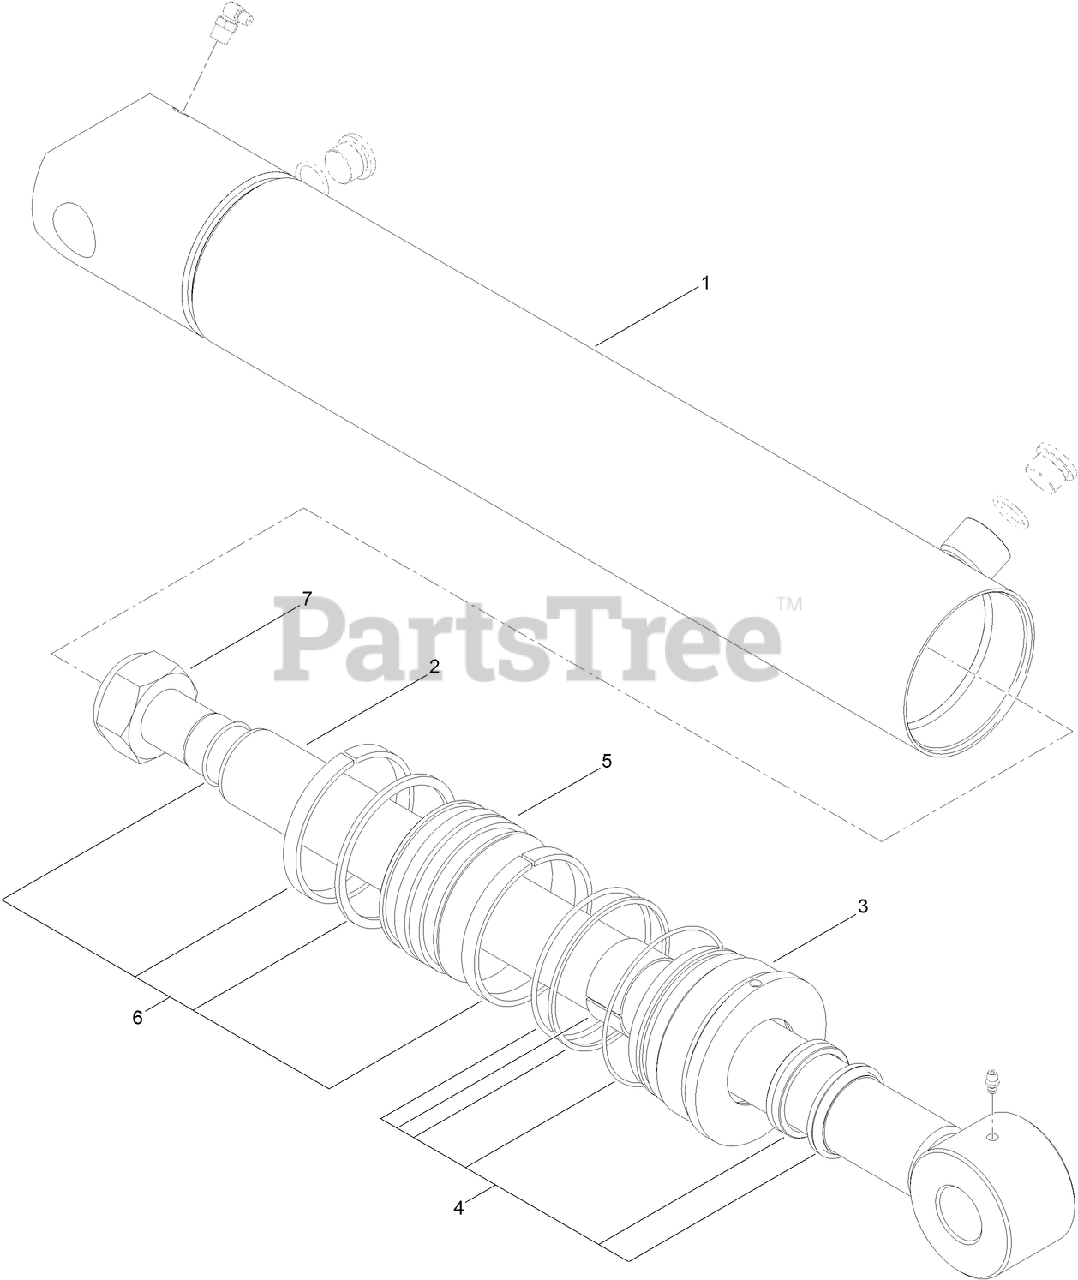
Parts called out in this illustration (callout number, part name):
1	TUBE-CYLINDER
2	ROD-CYLINDER
3	GLAND-CYLINDER
4	CYLINDER GLAND SEAL KIT
5	PISTON-CYLINDER
6	CYLINDER PISTON SEAL KIT
7	NUT-PISTON, CYLINDER
